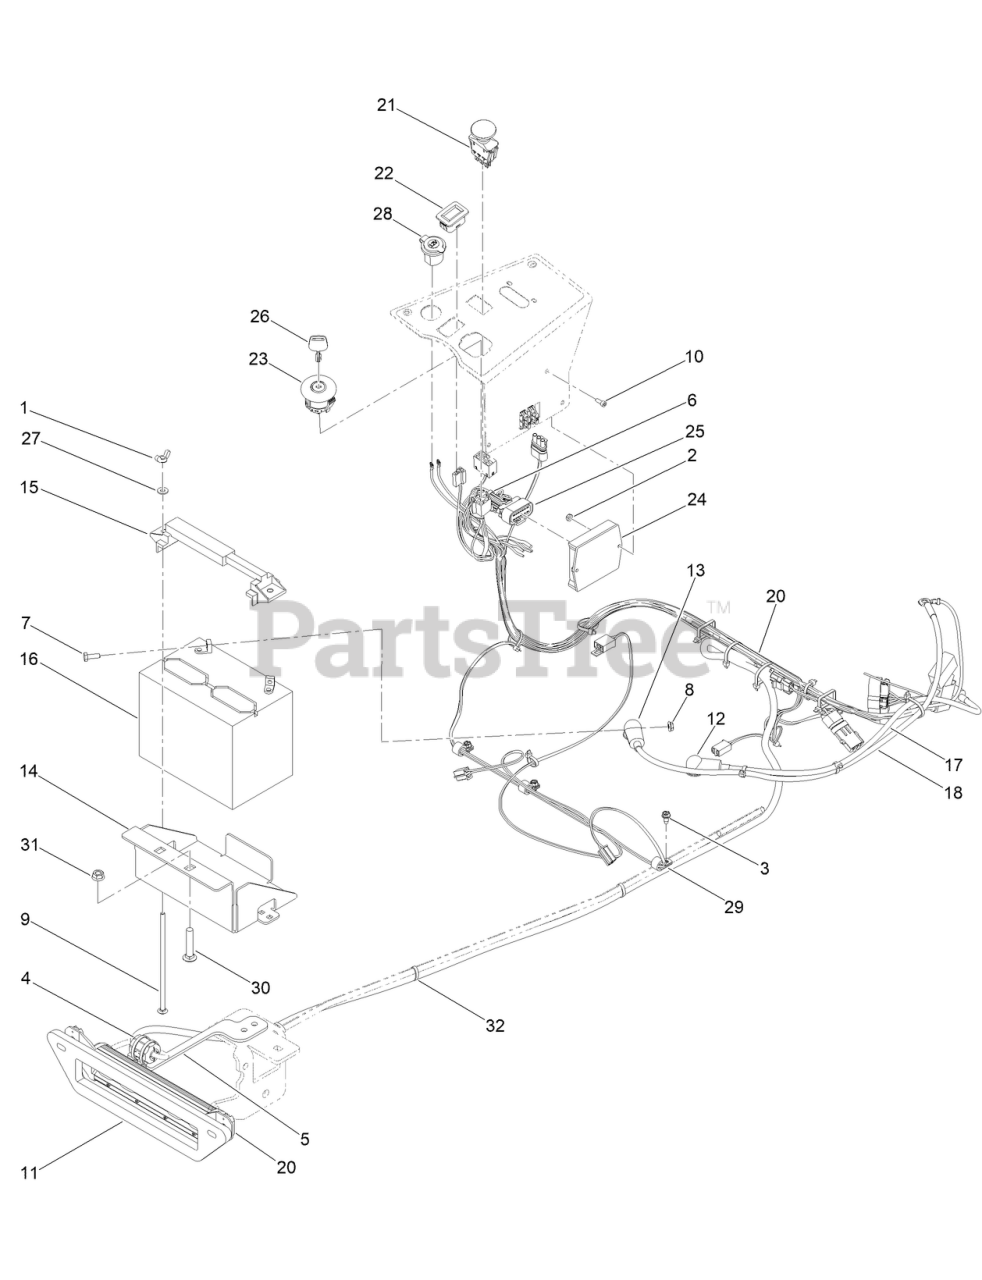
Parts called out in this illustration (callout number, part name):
1	NUT-WING
2	NUT-LOCK
3	SCREW-HWH
4	FAIR-RITE ROUND CABLE SNAP-IT SIZE B
5	FAIR-RITE BRACKET PAINTED
6	6IN (40 LB) CABLE TIE NYLON UV
7	SCREW-HH
8	1/4-20 HEX FLANGE NUT
9	1/4-20 X 7 CARRIAGE BOLT ZINC
10	10-24 X 1/2 SOCKET C/S 18-8 SS
11	MWR FT NYLON BUMPER
12	3.15 LGTH STRAIGHT INSUL TERM COVER RED
13	STRAIGHT INSULATING TERMINAL COVER
14	MWR BATTERY BOX
15	BATTERY HOLD DOWN
16	MWR START BATTERY 350CCA
17	MWR POSITIVE BATTERY CABLE 25IN
18	MWR NEGATIVE CABLE 28
20	FULL BEAM WITH LIGHTED HELMET LIGHT BAR
21	PTO SWITCH
22	HOUR METER
23	IGNITION SWITCH
24	INTERLOCK MODULE
25	MWR KEYSWITCH JUMPER HARNESS
26	2023 MWR KEY
27	WASHER-FLAT
28	12 VOLT AUXILLIARY PLUG
29	CLAMP-R
30	SCREW-CARR
31	3/8-16 HEX FLANGE NUT W/SERR ZINC YELLOW
32	TIE-CABLE
